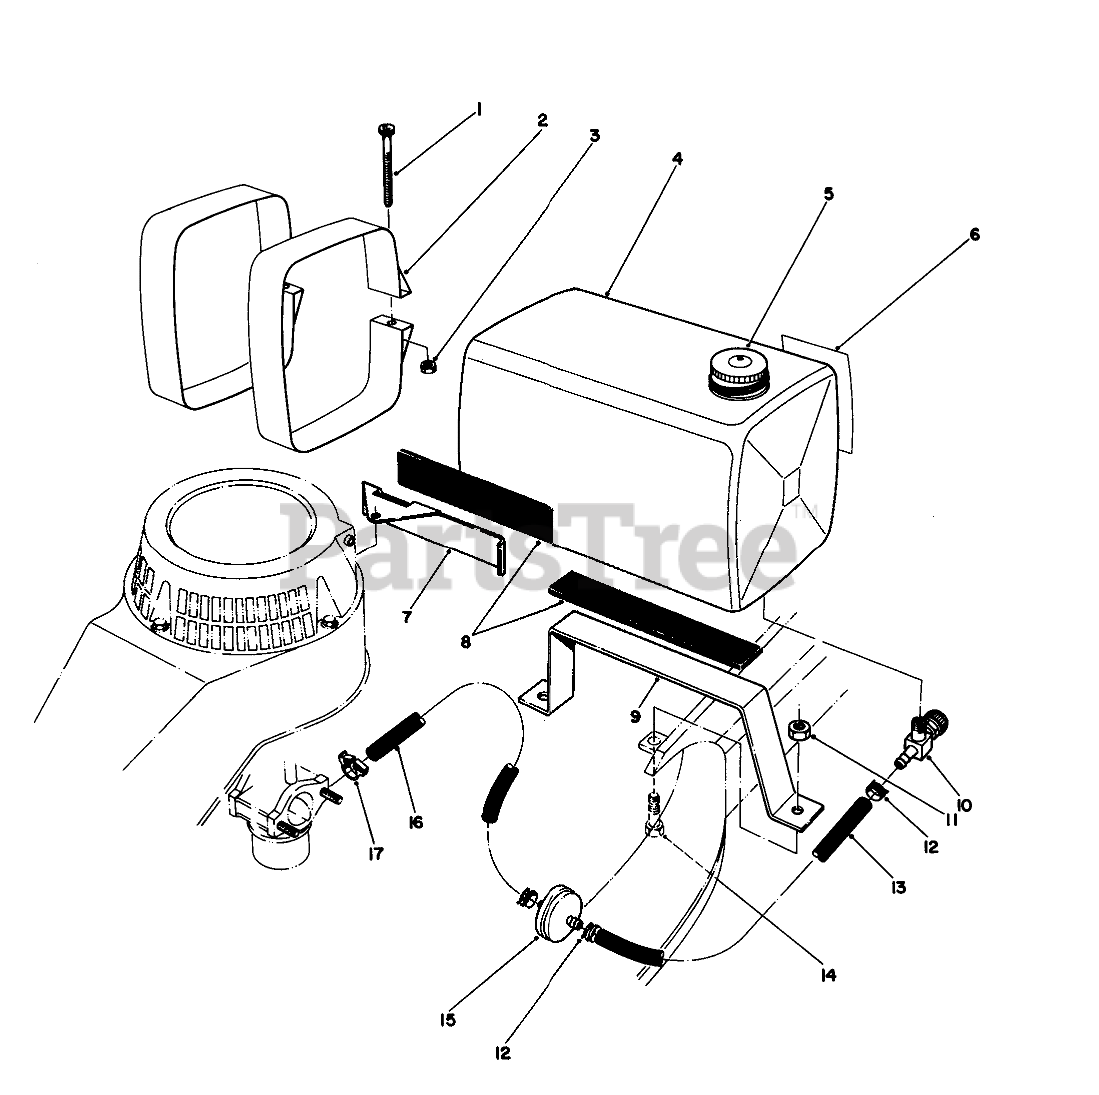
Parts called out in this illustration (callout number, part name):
1	SCREW-HSH
2	TANK MTG STRAP WA
3	NUT-HEX
4	Tank-Gas (Incl. Ref. #5)
5	CAP CAP
6	FUEL TANK DECAL
7	FRT TANK MOUNT
8	ISOLATOR PAD
9	BOTTOM TANK MOUNT
10	.125 ID SHUTOFF VALVE
11	NUT-LOCK, NI
12	Clamp
13	HOSE-FUEL
14	SCREW-HH
15	Nut
16	LINE-GAS
17	FUEL LINE CLAMP
